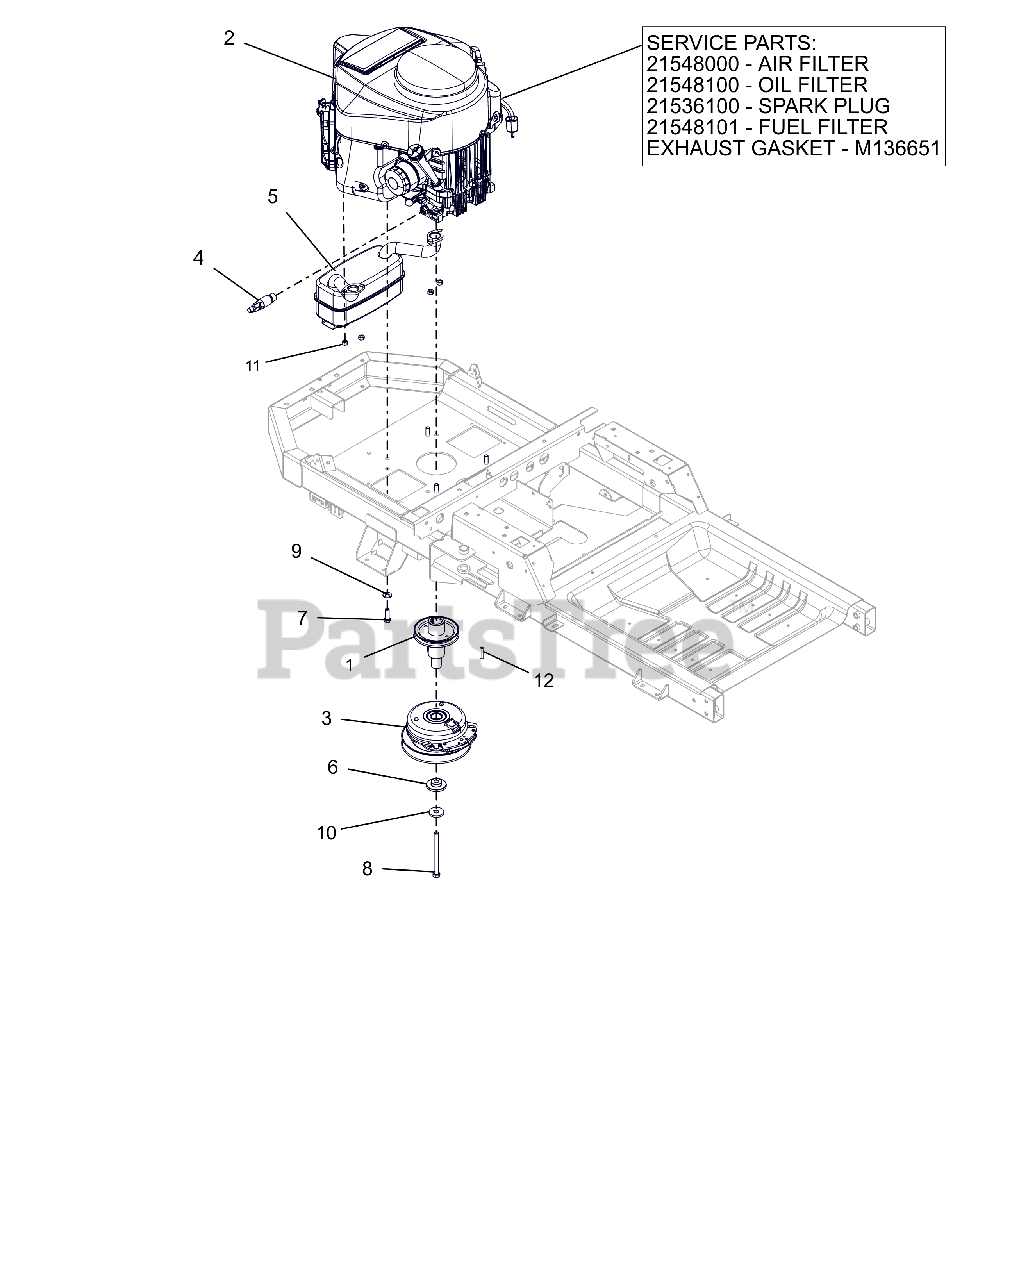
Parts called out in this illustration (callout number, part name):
1	WLDMT, DRIVE SHEAVE (LG XL)CZC
2	ENGINE, KAWASAKI FR730 24HP
2	AIR FILTER, KAWASAKI FR
2	OIL FILTER, KAWASAKI FR
2	PLUG, SPARK
2	FUEL FILTER-KAWASAKI FR
2	GASKET, MUFFLER #
3	CLUTCH,105FTLB MONOPOLE 6.83"
4	DRAIN, OIL M20X2.5
5	MUFFLER, KAWASAKI
6	BSHG-FLG .469X1.06X.574X2.0
7	BLT-HEX.38-16X1.25 G5YZ NYTORQ
8	BLT-HEX.438-20X5 GR8 YZ NYTORQ
9	WASHER, 3/8" SPRING DISC
10	WASHER, 7/16" SPRING DISK
11	NUT-LK-TOP M8-1.25 YWZC
12	KEY-SQ .25 X 1.25 X .25 SAE
